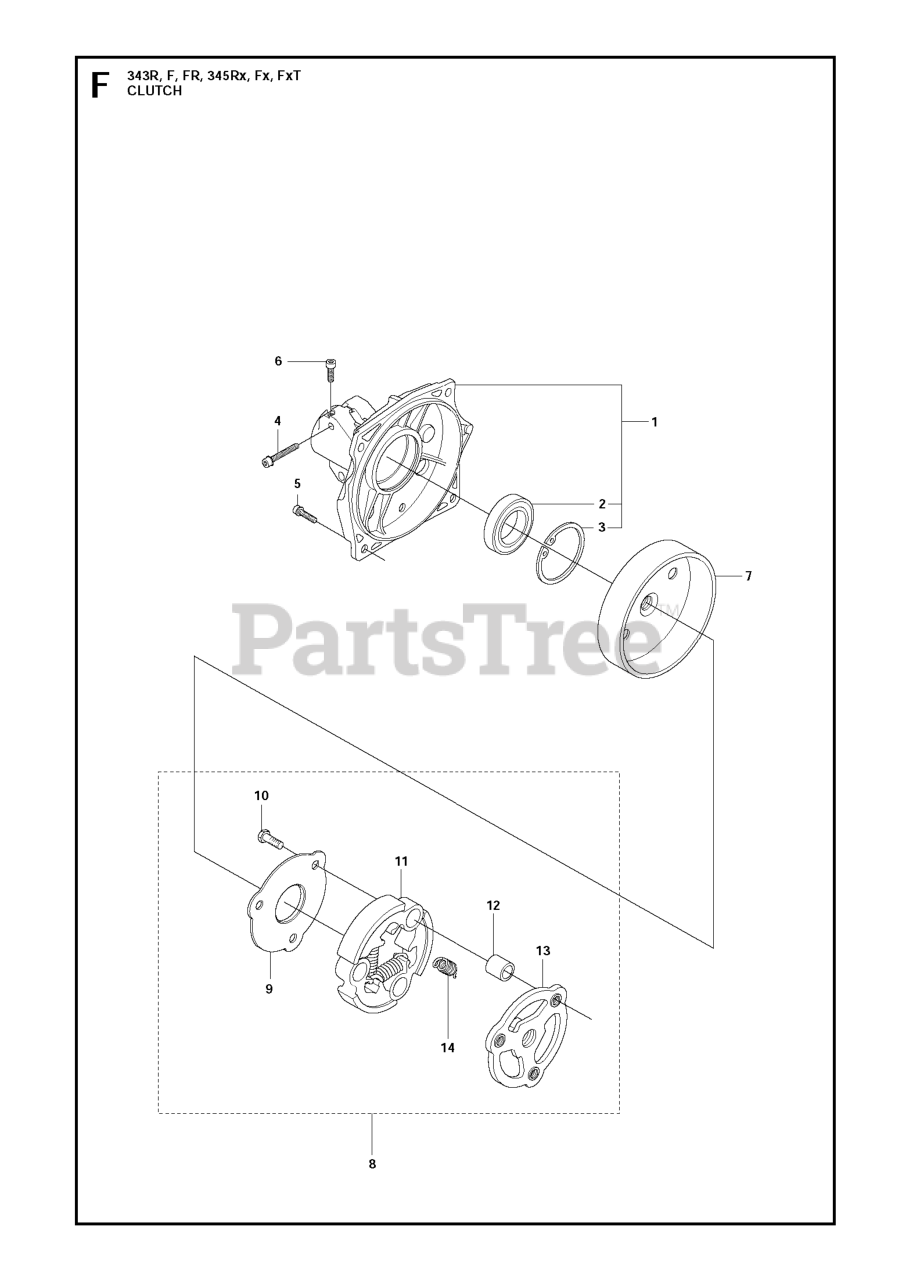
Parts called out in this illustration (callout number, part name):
1	CLUTCH COVER
2	BALL BEARING 6202-2RS1
3	RETAINING RING SGH 35
6	SCREW MC6LS 5X12
7	CLUTCH DRUM ASSM.
8	CLUTCH CPL
10	SCREW
14	CLUTCH SPRING
